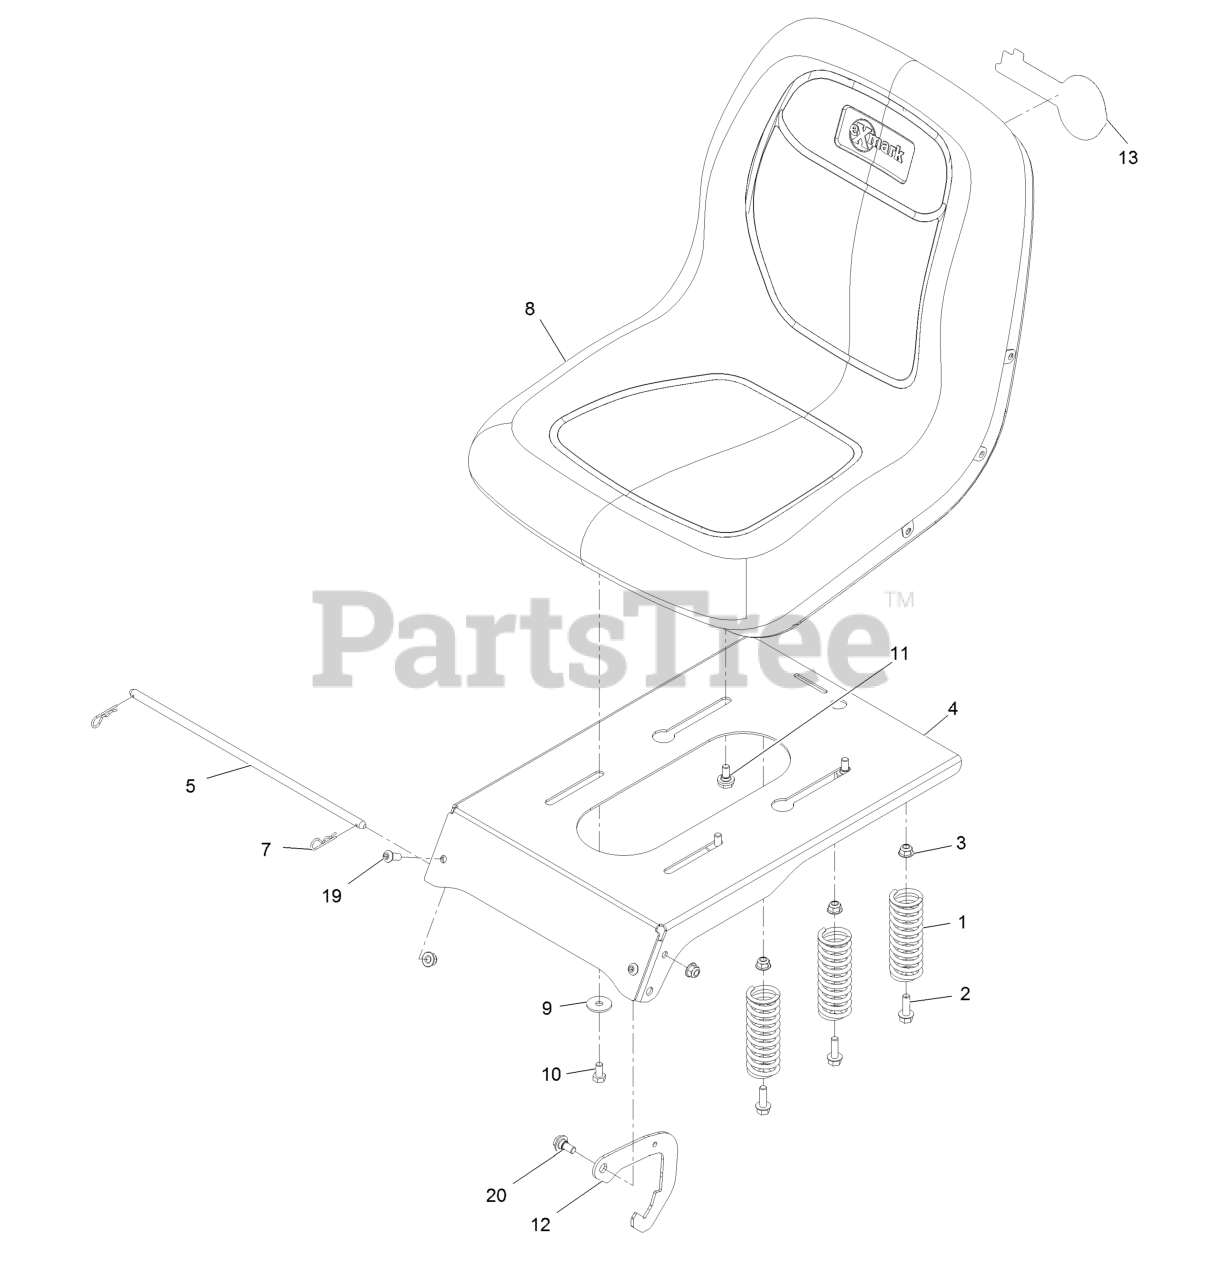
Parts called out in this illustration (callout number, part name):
1	SPRING-COMPRESSION
2	SCREW-HHF
3	NUT-HF, NI
5	ROD-PIVOT, NARROW
7	PIN-COTTER
8	SEAT-18 IN
9	WASHER-PIVOT
10	SCREW-HH
11	BOLT-SHOULDER,HFH
12	LATCH-SEAT
13	DECAL-EXMARK LOGO
19	SCREW-HSBH
20	SCREW-SHOULDER
